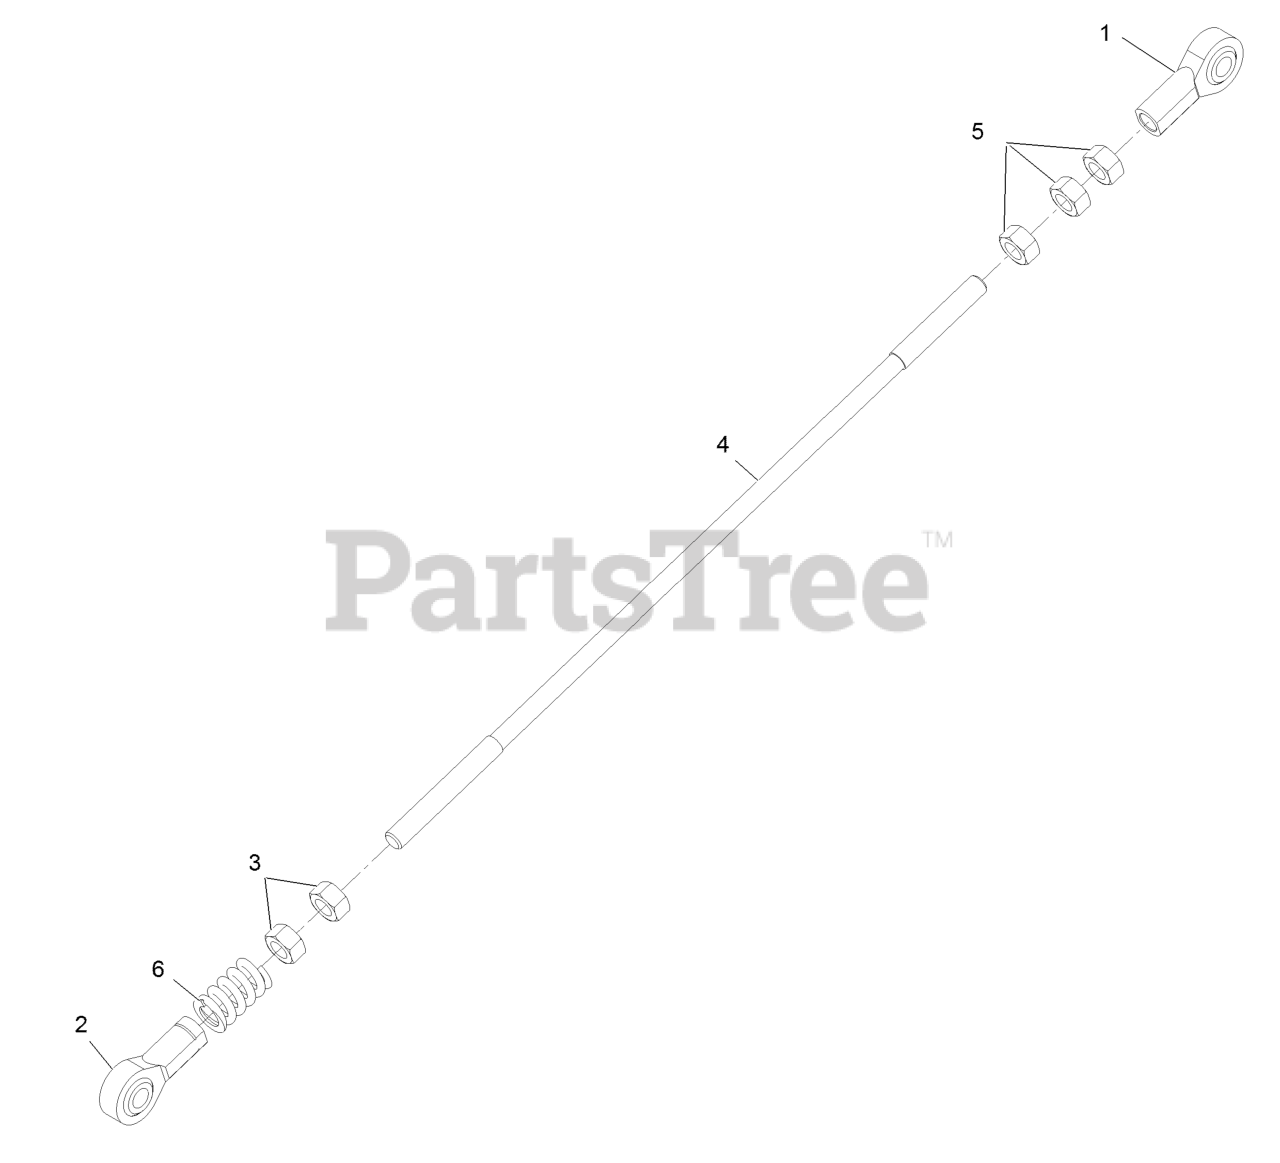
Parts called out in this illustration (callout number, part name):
1	BALLJOINT-RH
2	BALLJOINT-LH
4	LINK,XP HYDRO CONNECT RH
5	NUT-HEX
6	SPRING-COMPRESSION
